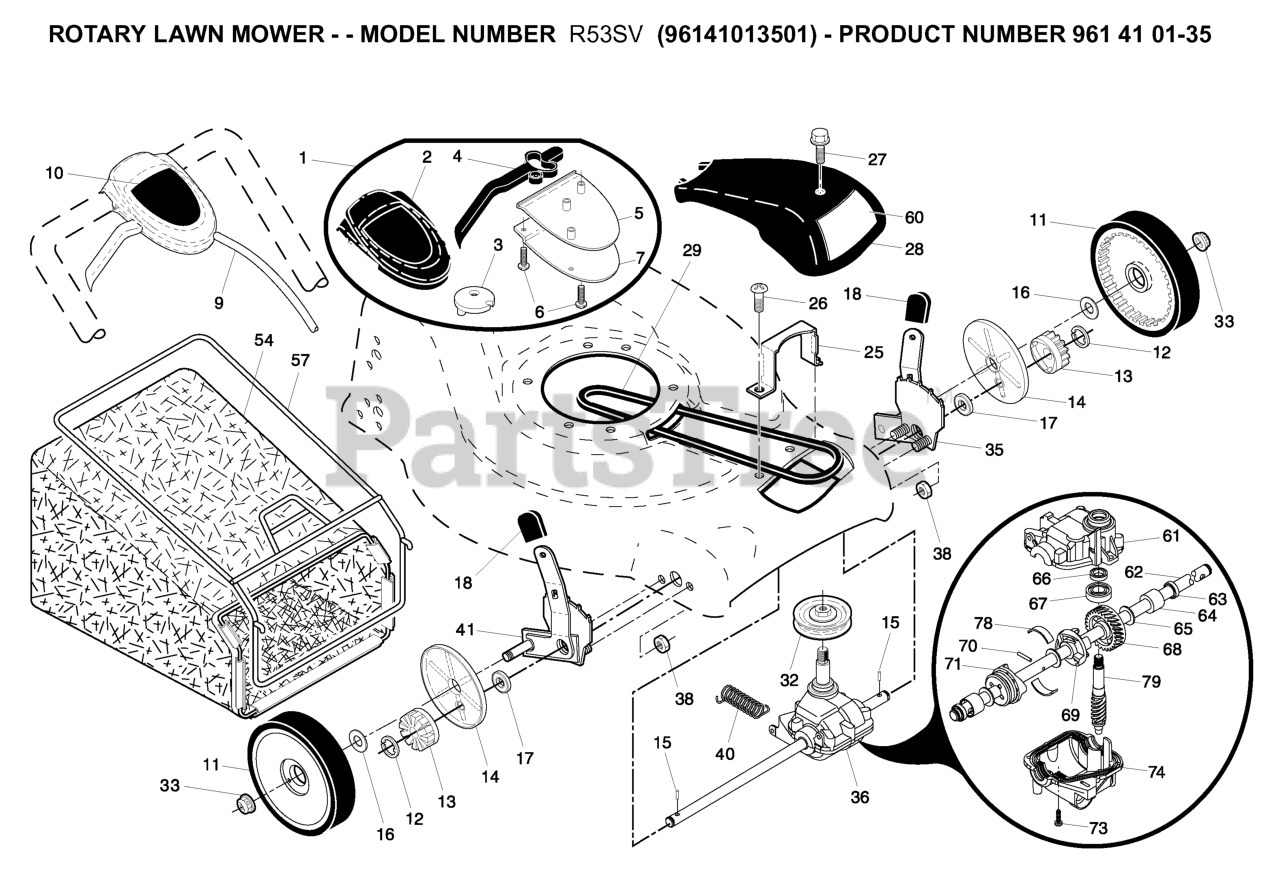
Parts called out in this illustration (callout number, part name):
1	DRIVE CONTROL ASSEMBLY (INCLUD
2	COVER TOP AUTO WALK CONTROL
3	PULLEY.CAM.DRIVE.CONTROL.EZ
4	LEVER, AUTOWALK DRIVE CONTROL
5	COVER BOTTOM AUTO WLK CONTROL
6	SCREW, PHILLIPS HEAD 10 X 5/8
7	BRACKET.DRIVE.CONTROL.MOUNT.BL
9	CABLE ASSEMBLY, DRIVE
10	DECAL, DRIVE
11	WHEEL.8X1.75.MAG2.RAD3.GRY
12	E-RING 7/16 RE
13	PINION.14.TEETH.FGD
14	COVER.DUST.WHEEL
15	PAWL.DRIVE
16	WASHER FLUT
17	BEARING ASM
18	SELECTOR KNOB
25	BELT KEEPER
27	SCREW, HEX HD TAPPING #10-24 1
28	COVER.DRIVE.21.FWGD.GRAY
29	BELT.DRIVE.FG
32	RP PULLEY.DRIVE.EZ
33	NUT.HEX.FLANGE.3/8-16.LO(3 2)
35	KIT, WHEEL ADJUSTER, LH
36	TRANSMISSION.21.FGD.HT.VST
38	LOCKNUT.NYLOC.1/4-20
41	KIT, WHELL ADJUSTER, RH
54	Grassbag Assembly
57	FRAME, GRASSBAG
60	DECAL DRIVE COVER
61	CASE.UPPER.00254(SERVICE)
62	SHAFT OUTPUT (12289)
63	SEAL.OUTPUT.SHAFT
66	SEAL INPUT SHAFT
68	GEAR 28 TEETH 36208
69	FIXED DOG CLUTCH
70	PIN.3.50.33733
71	MOVEABLE DOG CLUTCH
74	CASE.BOTTOM.
78	SPRING LEAF
79	SHAFT WORM
